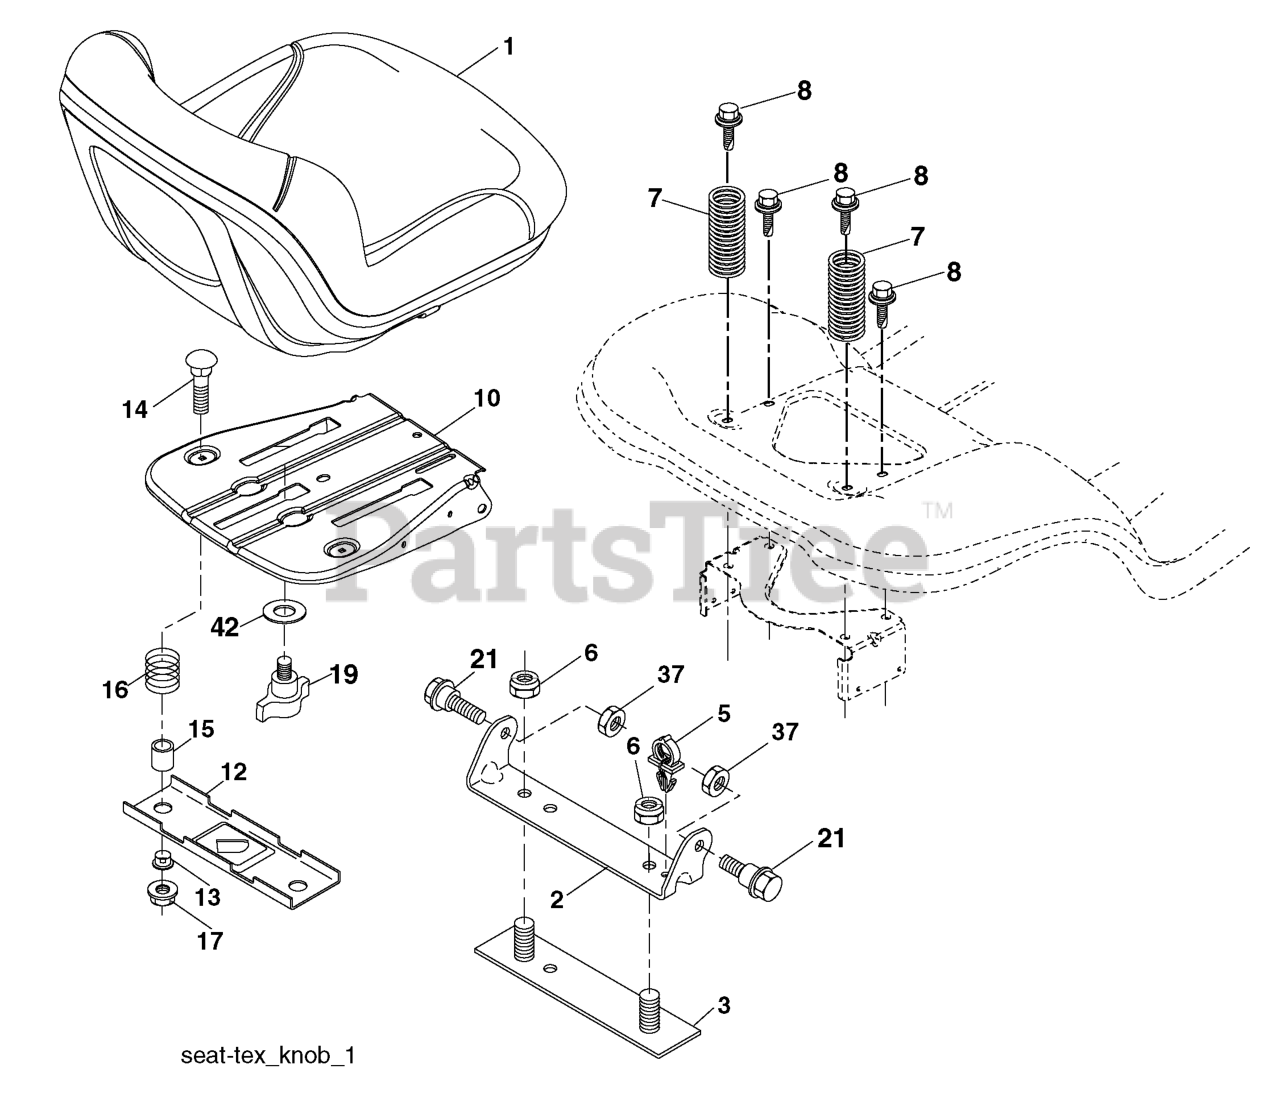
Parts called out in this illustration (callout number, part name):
1	RP SEAT.TH130.GRY.MILSCO.
2	BRKT.PIVOT.FENDER
3	STRAP
6	NUT
7	SPRING COMPRESSION
8	BOLT.5/16-18UNCX3/4 W/SEMS.BLK
10	PAN.ASM.SEAT.SHORT
12	BRKT.MNT.OPC.SW.SEAT.
14	BOLT.ROUND.HEAD.SQUARE.NECK
15	SPACER SPLIT 28X.96
16	SPRING COMPRESSED
17	NUT T
19	KNOB.SEAT.ADJ.
21	BOLT.SHOULDER.5/16-18
37	NUT.71038.31-18.HEX.NYLOCK
42	WASHER.CUP.SEAT.
